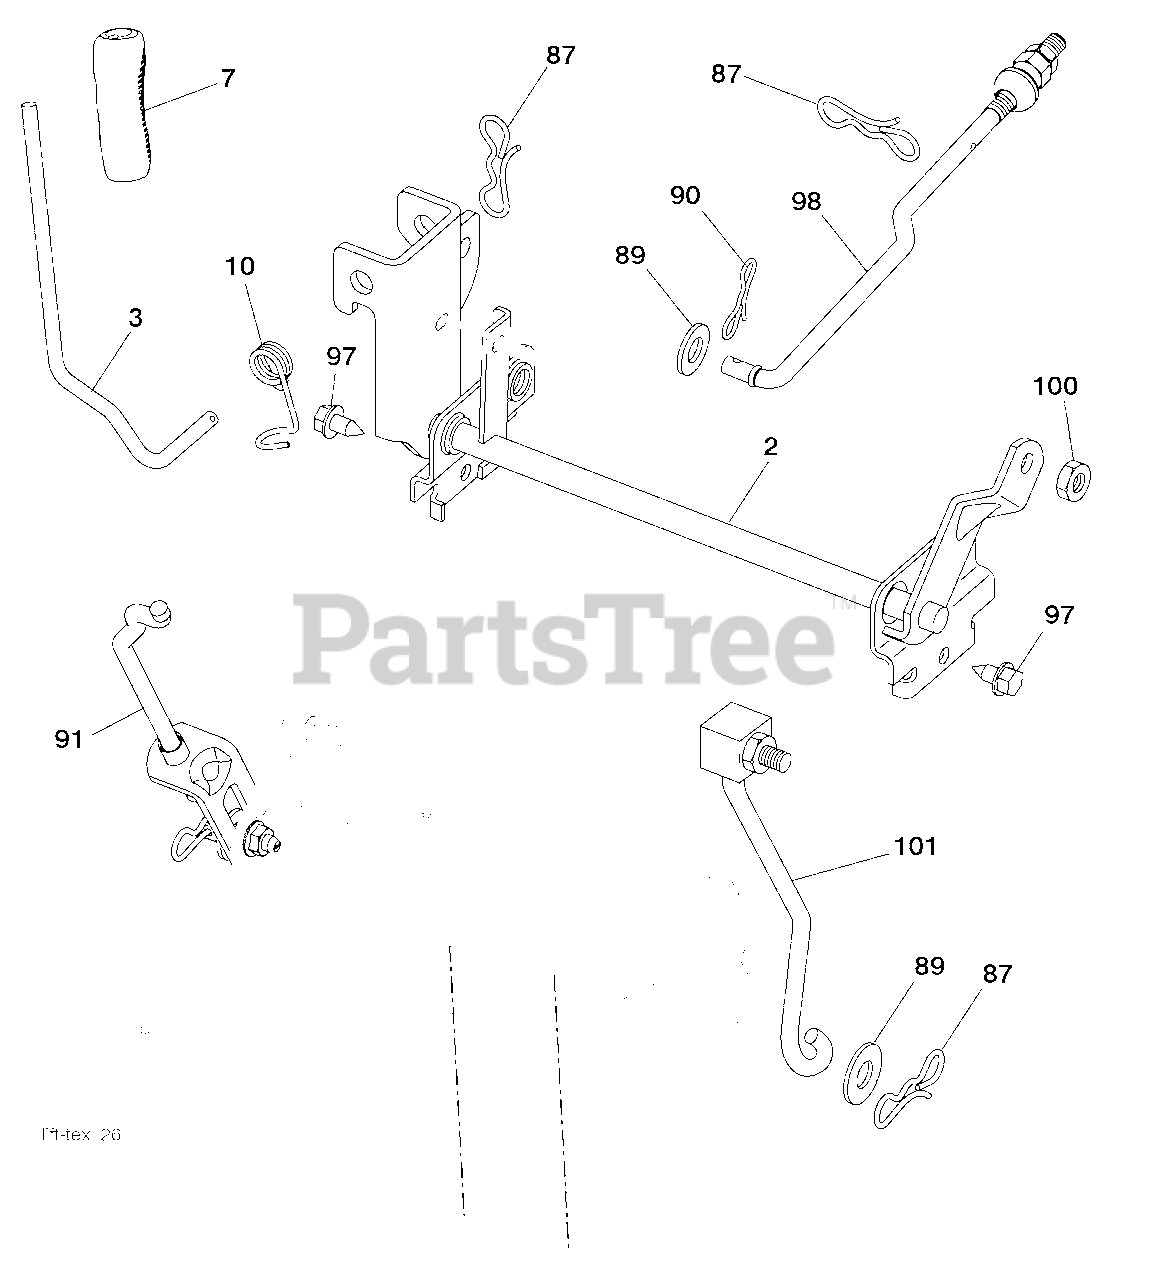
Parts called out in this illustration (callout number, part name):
2	Shaft Asm., Lift
3	Lever Asm., Lift RH
7	Grip, Lever
10	Spring Torsion
87	Pin Cotter 7/16 Bow Tie Lock
89	Washer Clear Zinc
90	Pin Cotter 5/16 Bow Tie Lock
91	Link Asm Lift LH Rear
97	Screw Hex Wsh. THDR 3/8-16 x 3/4
98	Link Lift Susp. Front Mower
100	Nut Centerlock 3/8-16 unc
101	Link Asm. Lift FXD
